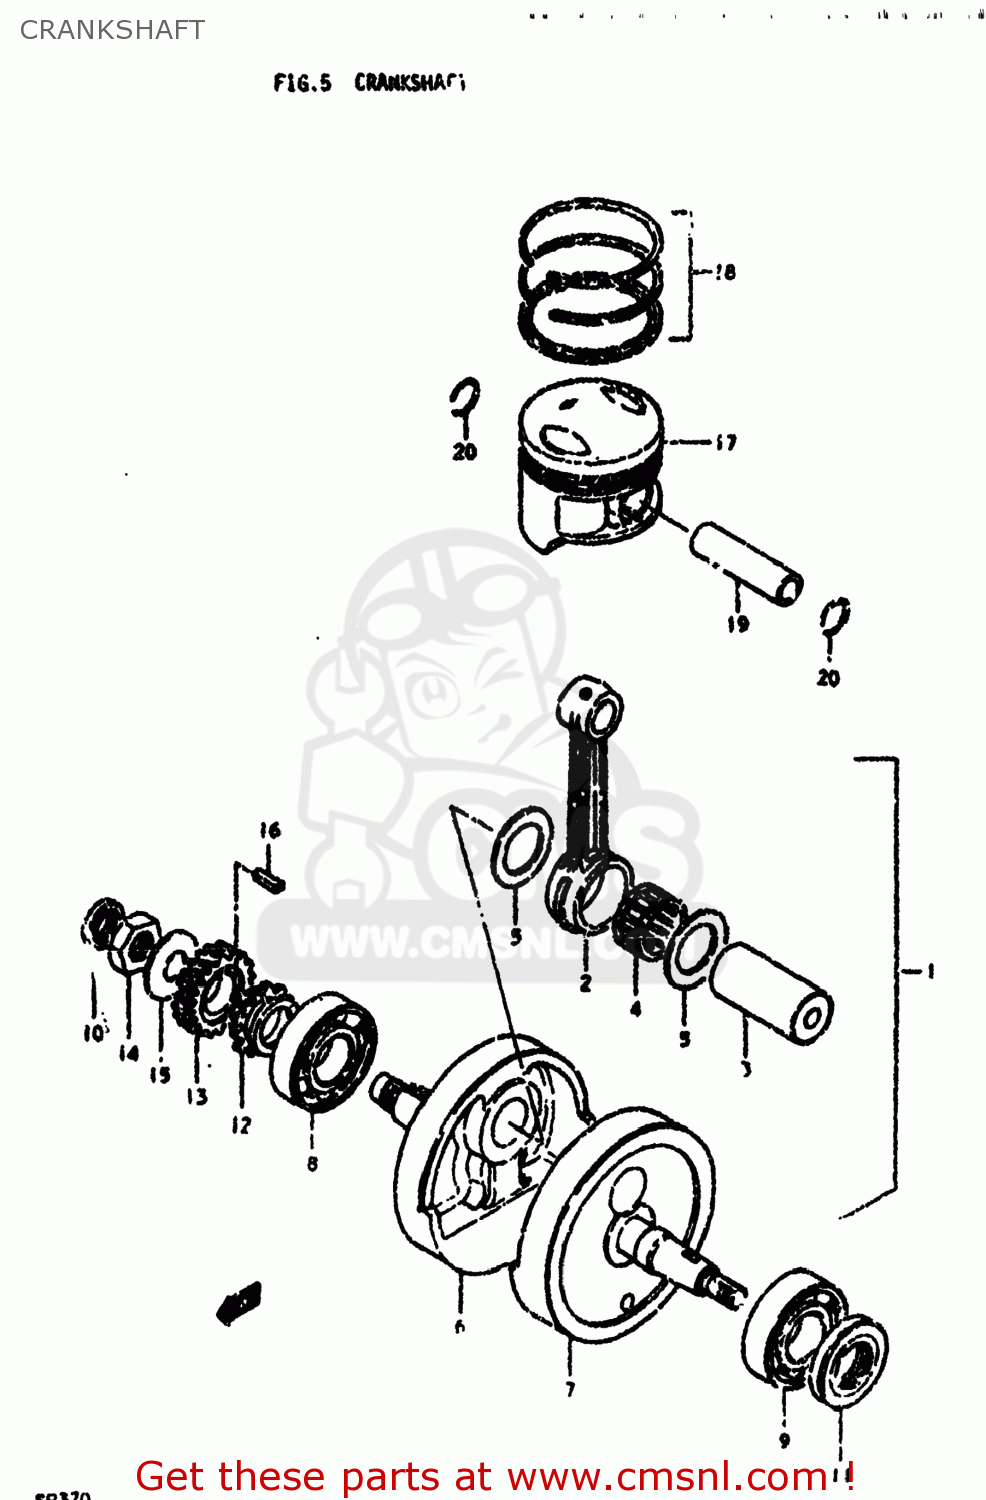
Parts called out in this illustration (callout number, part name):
1	CRANKSHAFT ASSEMBLY
2	ROD,CONNECTING
3	PIN,CRANK
4	BEARING
5	WASHER (32X50X1)
6	CRANKSHAFT
7	CRANKSHAFT,LEFT
8	BALL BEARING 30X72X19
9	BEARING
10	SEAL,OIL(16X30X6)
11	SEAL,OIL(30X58X7)
12	SPROCKET,CAM CHAIN DRIVE
13	GEAR,PRIMARY DRIVE
14	NUT (20MM)
15	WASHER
16	KEY
17	PISTON
18	RING SET,PISTON
19	PIN,PISTON
20	CIRCLIP
